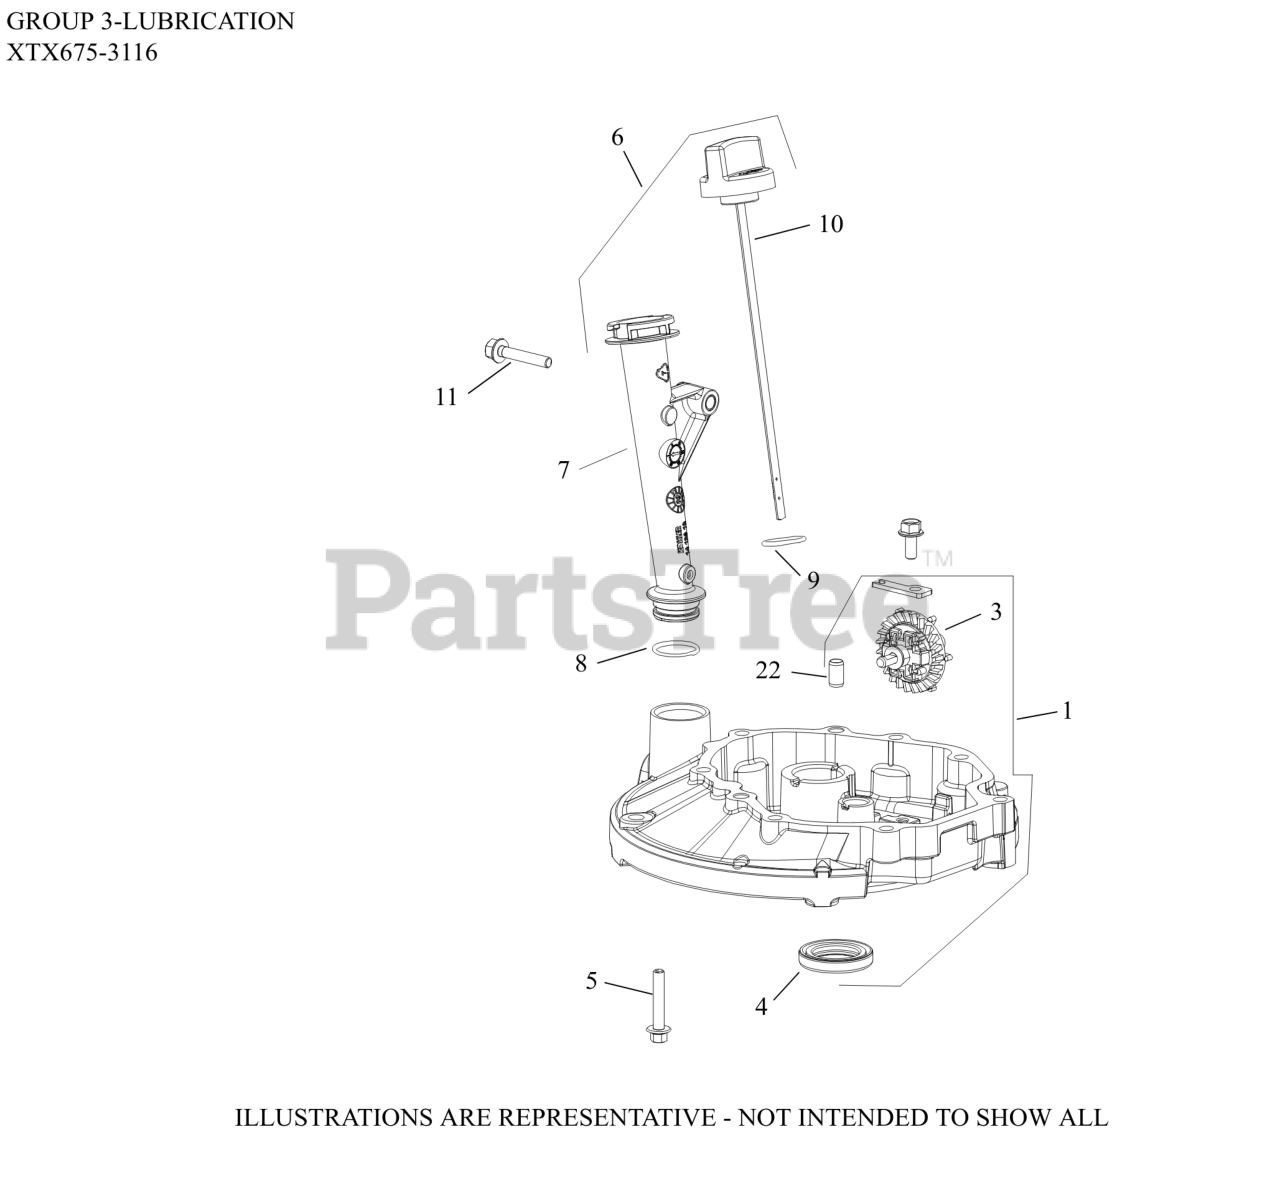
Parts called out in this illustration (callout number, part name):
1	KIT, OIL PAN
3	GEAR ASSEMBLY, GOVERNOR
5	SCREW, HEX FLANGE (M6)-(#25086434S)
6	KIT, DIPSTICK AND TUBE-(#1412320S)
7	TUBE ASSEMBLY, OIL FILL
8	O-RING, OIL FILL TUBE
9	O-RING (CAP)
10	CAP, DIPSTICK ASSEMBLY
11	SCREW, HEX FLANGE (M6)-(#25086435S)
22	PIN, DOWEL (8mm)
